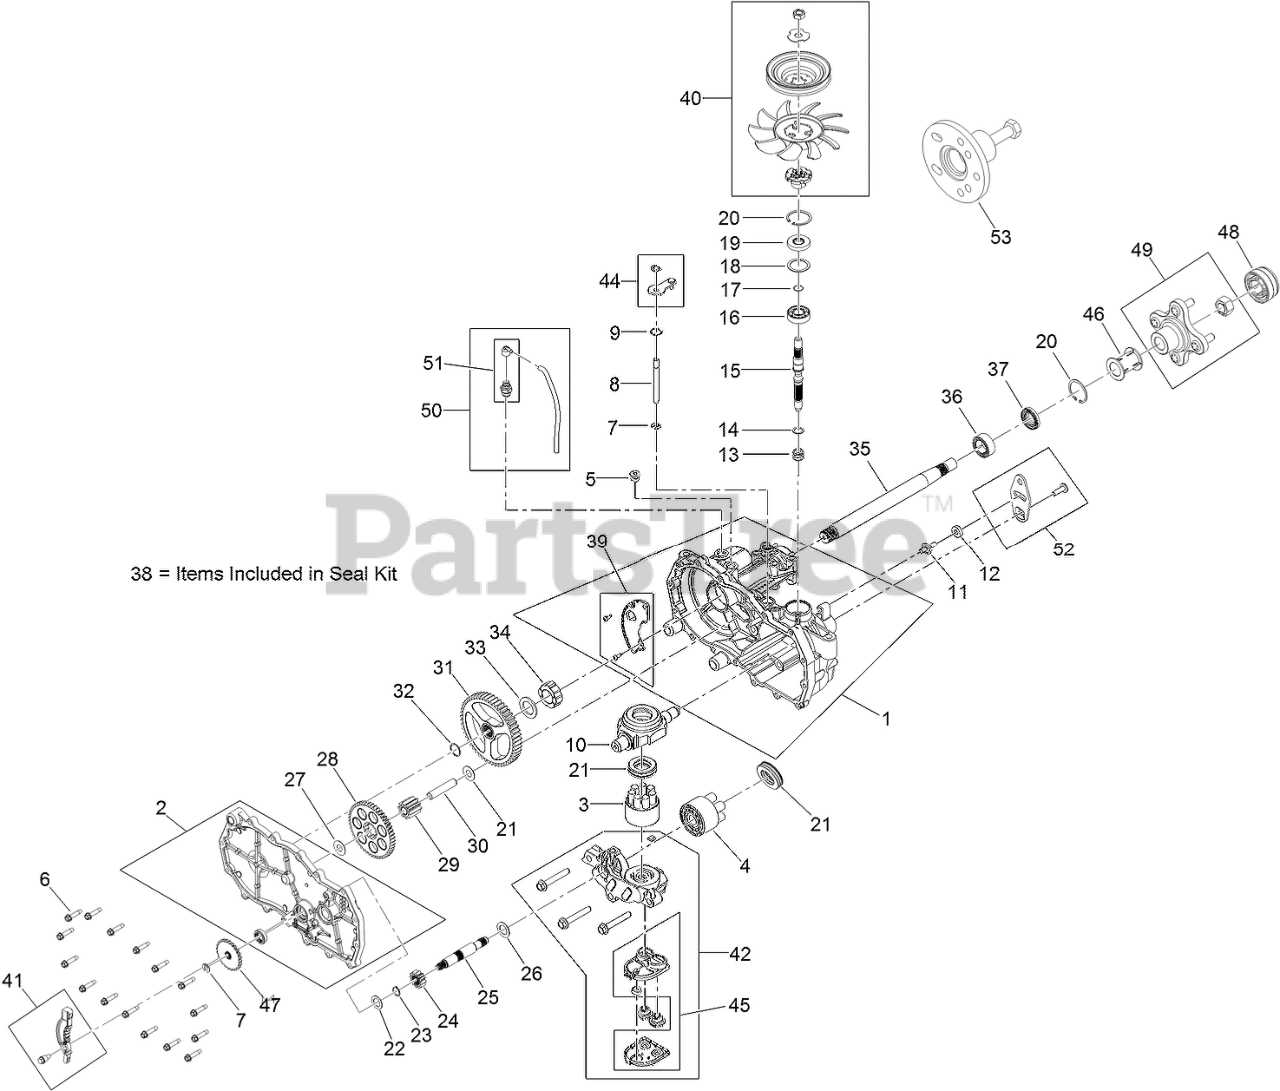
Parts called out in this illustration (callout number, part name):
1	MAIN HOUSING ASM
2	SIDE ASM
3	PUMP BLOCK ASM
4	CYLINDER BLOCK KIT
5	PLUG-THREAD, STRAIGHT
6	SCREW-HHF
7	RING-RETAINING, EXTERNAL
8	ROD-BYPASS
9	RING-RETAINING, INTERNAL
10	SWASHPLATE-TRUNNION
12	PUCK-FRICTION
13	SPRING-BLOCK
14	WASHER-THRUST
15	SHAFT-INPUT
16	BEARING-BALL
17	RING-RETAINING
18	SPACER
19	SEAL-LIP
20	RING-RETAINING
21	BEARING-THRUST
22	WASHER-FLAT
23	RING-RETAINING
24	GEAR-12T
25	SHAFT-MOTOR
26	WASHER
27	WASHER
28	GEAR-49T
29	GEAR-JACKSHAFT, 10T
30	PIN-JACKSHAFT
31	RING-SPIRAL, RETAINING
32	GEAR-52T, BULL
33	WASHER
34	BEARING-SLEEVE
35	SHAFT-AXLE
36	BUSHING-AXLE
37	SEAL-LIP
38	SEAL KIT
39	EXPANSION PLATE KIT
40	FAN PULLEY KIT
41	BRAKE ARM KIT
42	CENTER SECTION FILTER KIT
44	BYPASS ARM KIT
45	FILTER KIT
46	TUBE-AXLE
47	DISC-BRAKE, COG
48	COVER-NUT, AXLE
49	HUB KIT
50	BREATHER KIT
51	BREATHER ASM
52	CONTROL ARM KIT
53	PULLER-HUB, 4 BOLT
